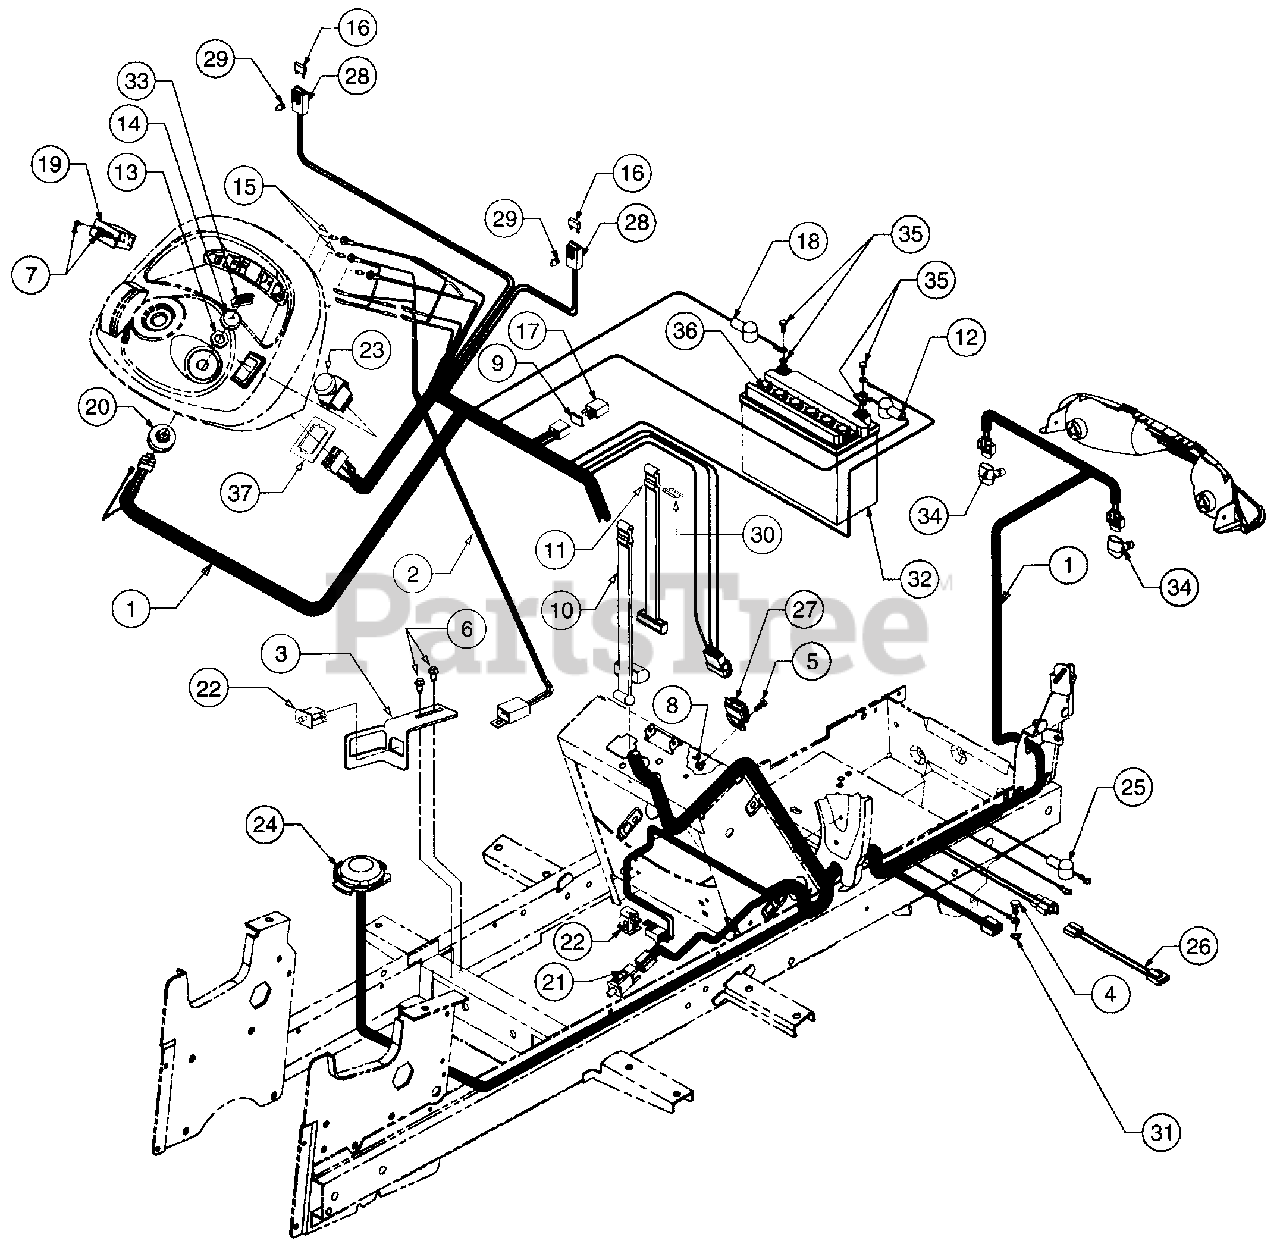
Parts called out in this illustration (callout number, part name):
1	Wire Harness, Main
2	Wire Harness, Indicator Light
3	Bracket, Clutch Switch
4	Screw, Hex Cap, 5/16-24 x .62
5	Screw, Hex Cap, 1/4-20 x .625 GR5
6	Screw, Hex Wash Hd Tapp, 1/4-20 x .5
7	Screw, Truss Hd Tapp, #6 x .62
8	Nut, Hex Sems, 1/4-20
9	Gasket, Silicone
10	Strap, Battery Retainer
11	Strap, Battery Retainer
12	Cover, Terminal Black
13	Nut, Ignition Switch
14	Cap, Ignition Switch
15	Bulb, Indicator
16	Fuse, 20 Amp
17	Relay
18	Cover, Terminal Red
19	Hour Meter
20	Switch, Ignition
21	Switch, Interlock (Brake)
22	Switch, Snap Mount - Normally Closed
23	Switch, PTO
24	Switch, Seat
25	Cover, Terminal Red
26	Adapter, PTO Harness
27	Module, Voltage Sensor
28	Holder, Fuse
29	Clip, Fuse Holder Mounting
30	Hook, Wire Rectangular
31	Washer, External Lock, 5/16
32	Battery
33	Key, Ignition
34	Bulb, Head Lamp
35	Battery Cable Hardware
36	Cap, Battery
37	Bracket, PTO Switch Retainer
